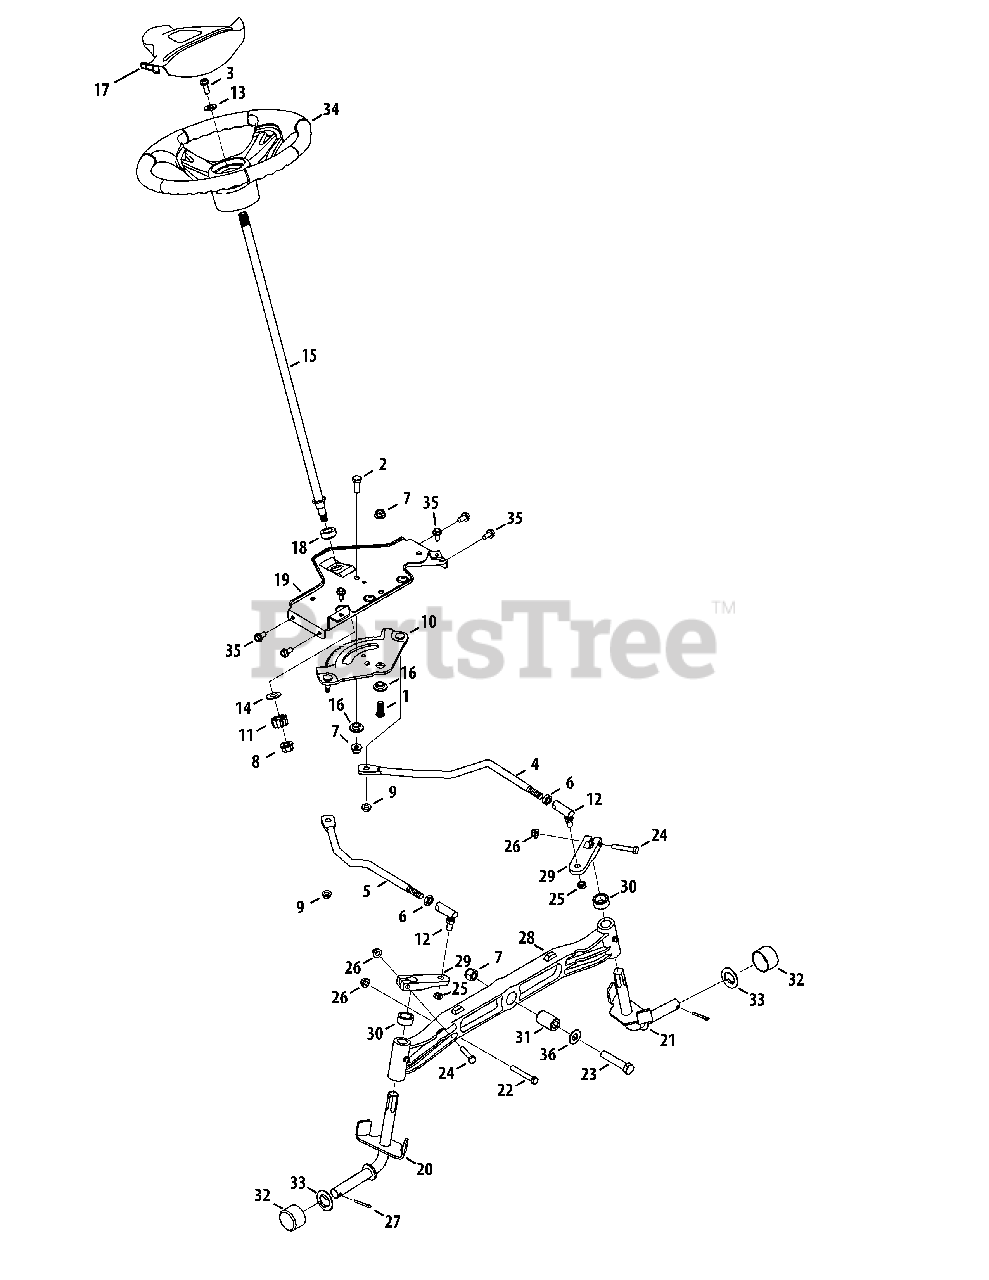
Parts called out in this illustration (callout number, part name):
1	Hex Screw, 3/8-16, 1.00, Gr5, Spec
2	Hex Screw, 3/8-16, 1.00, Gr5, Std
3	Hex Screw, 5/16-18, .875, Gr5, Lock
4	Link, Drag LH
5	Link, Drag RH
6	Nut, Jam, 7/16-20, Gr2
7	Nut, Flange Lock, 3/8-16, Grf,
8	Nut, Flange Lock, 7/16-20, Grb, Lock
9	Nut, Flange Lock, 5/16-18, Gr5, Sd Lk
10	Gear, Steering, 11/90 Ratio
11	Gear, Pinion, Steering
12	Ball Joint, 7/16-20, Lock
13	Washer, Flat, .406 x .875 x .105
14	Washer, Flat, .51 x 1.12 x .06
15	Shaft, Steering, .625 OD x 25, Cub
16	Spacer, Shoulder, .385x 1.25 x .3025
17	Cover, Steering Wheel, Cub Cadet
18	Bearing, Flange, Hex 5/8 Pm
19	Bracket, Support, Steering
20	Axle Ass’y, RH .750 Dia.
21	Axle Ass’y, LH .750 Dia.
22	Hex Screw, 5/16-18, 2.25, Gr5, Std
23	Hex Screw, 3/8-16, 2.50, Gr5, Std
24	Hex Screw, 5/16-18, 1.75, Gr5, Std
25	Nut, Hex Lock, 3/8-24, Grb
26	Nut, Flange Lock, 5/16-18, Grf
27	Pin, Cotter, 5/32, 1.25
28	Axle, Pivot Bar, Cast
29	Steering, Block
30	Spacer, .71 ID x .125 OD x .56
31	Spacer, .385 x 1.00 x 1.5075
32	Cap, Bumper
33	Washer, Flat, .350 x 1.559 x .062
34	Wheel, Steering, 3 Spoke, Softgrip
35	Screw, Self-tapping, 5/16-18, .750,
36	Flat Washer, .406 x .875 x .059
